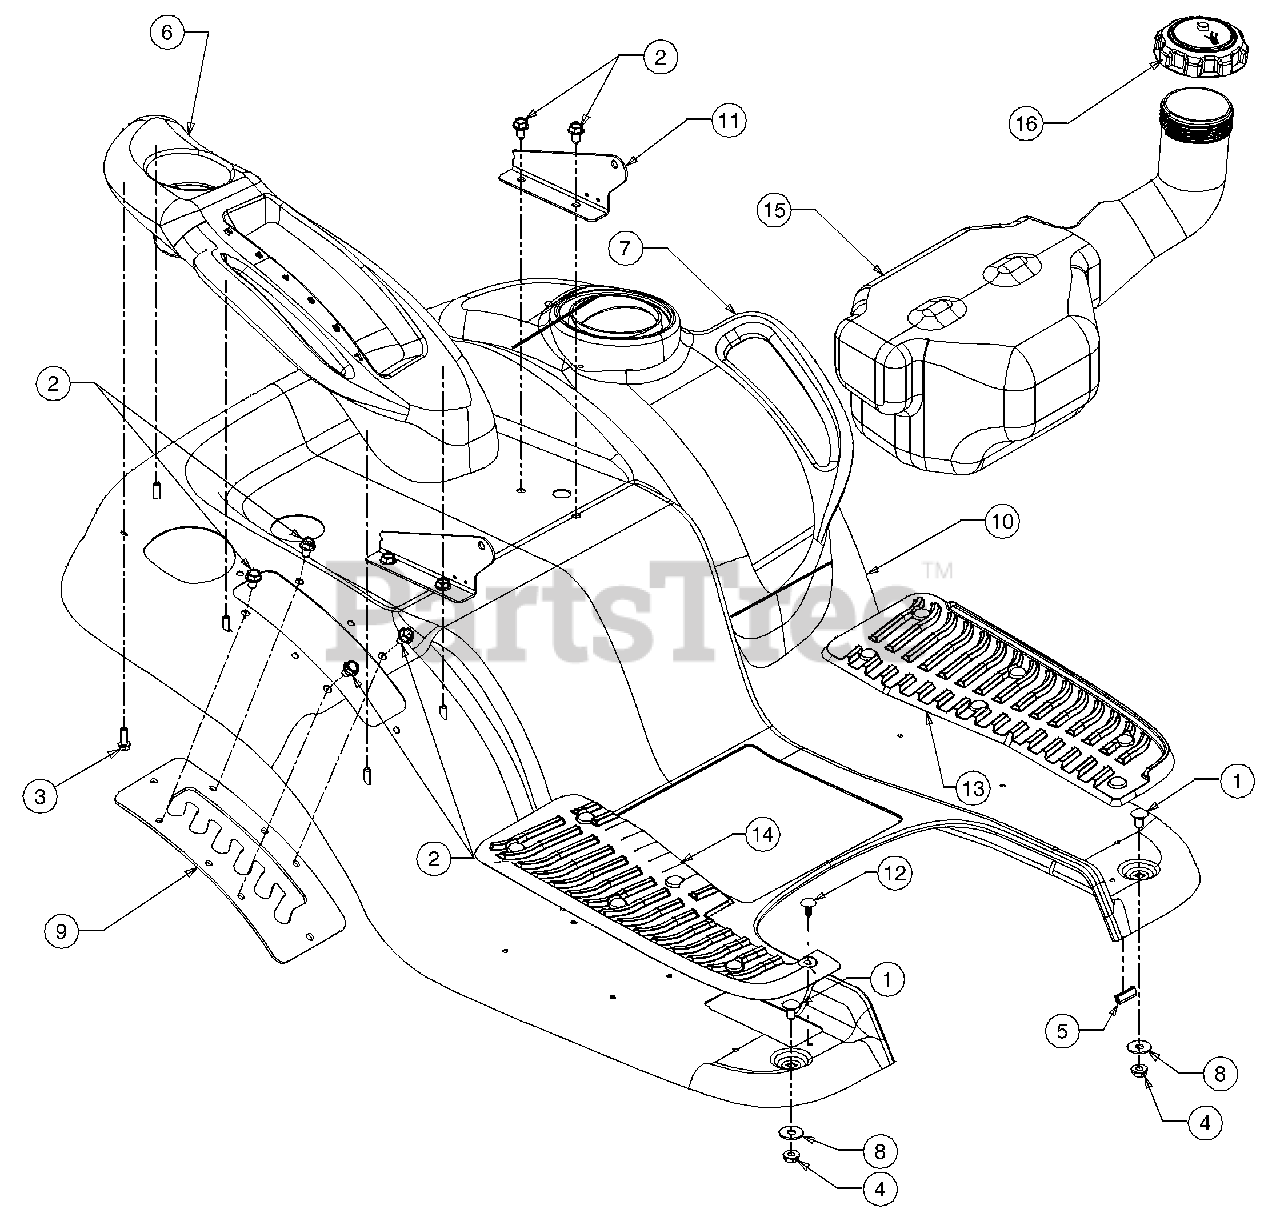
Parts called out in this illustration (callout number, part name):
1	Bolt, Carriage, 5/16-18 x .62 Lg
2	Screw, 5/16-18, 0.625
3	Screw, 1/4-15, 0.750
4	Nut, Flange Lock, 5/16-18
5	Strip, Trim
6	Cover, Fender, RH
7	Cover, Fender, LH
8	Washer, Flat, .349 x 1.00 x .063
12	Clip, Ratchet, .250 Dia
13	Pad, Foot, LH
14	Pad, Foot, RH
15	Tank, Fuel
16	Cap, Fuel
